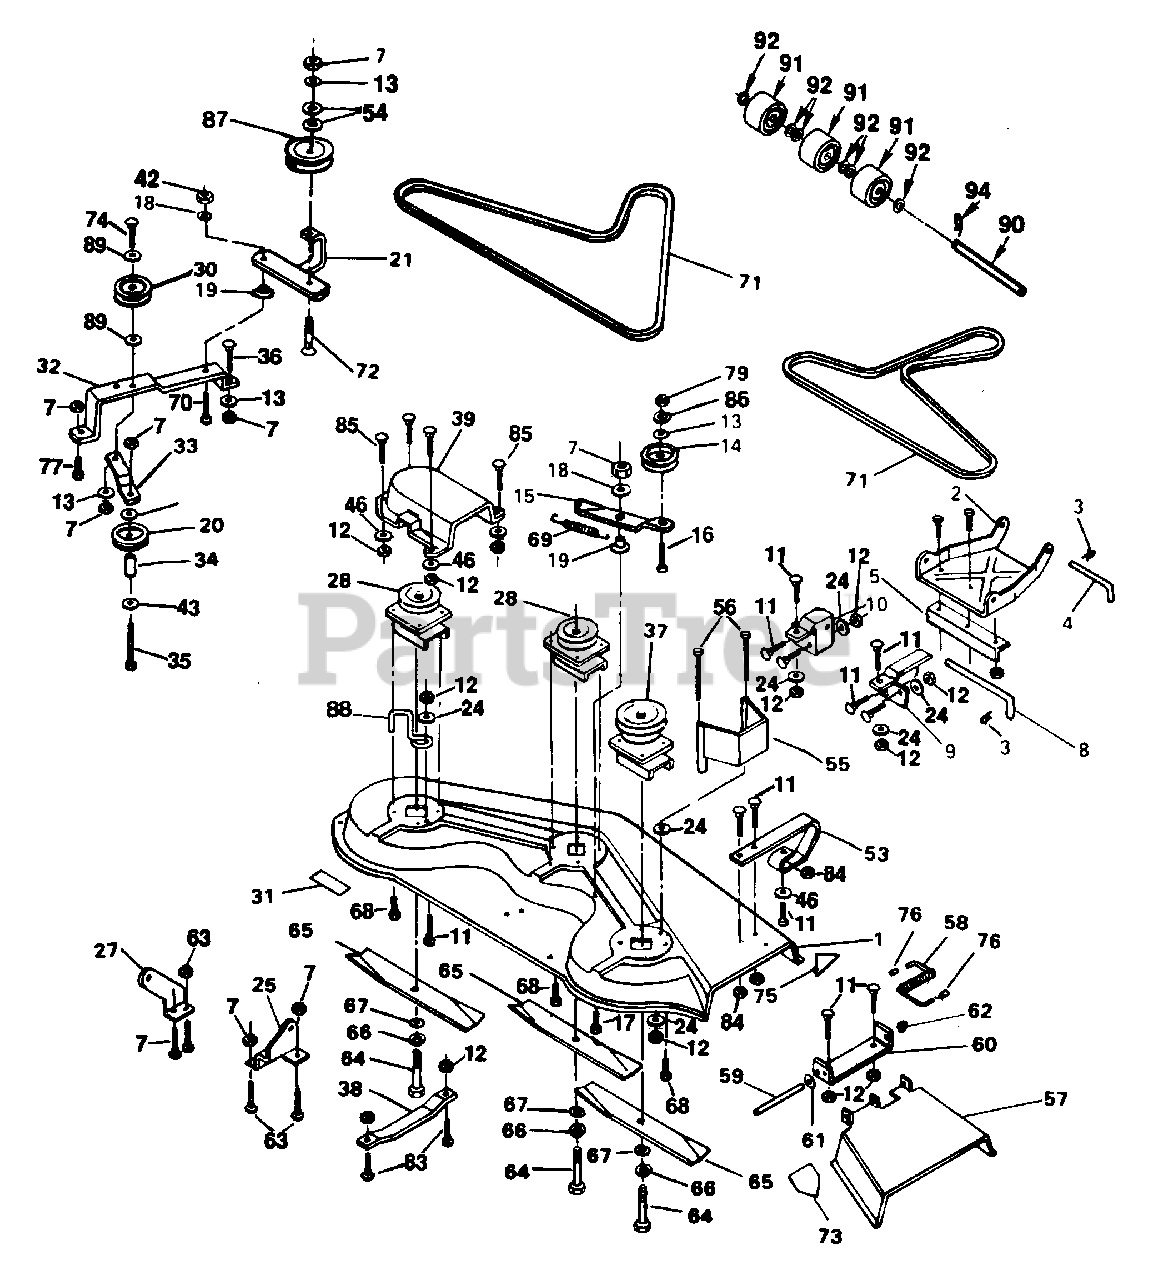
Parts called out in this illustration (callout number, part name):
1	Mower Housing (AYP part number)
2	Parallel Link (AYP part number)
3	Spring Retainer (AYP part number)
4	Front Hinge Pin (AYP part number)
7	Locknut
8	Rear Hinge Pin (AYP part number)
9	R.H. Lift Bracket (AYP part number)
10	L.H. Lift Bracket (AYP part number)
11	Carriage Bolt 5/16-18 x 3/4
12	Locknut
13	Washer (AYP part number)
14	Flat Idler (AYP part number)
15	Deck Arm Idler (AYP part number)
17	Hex Bolt 3/8-16 x 1-1/4 (AYP part number)
18	Wear Washer (AYP part number)
19	Spacer (AYP part number)
20	Idler Pulley (AYP part number)
21	Idler Arm (AYP part number)
24	Washer (AYP part number)
25	R.H. Rear Suspension Bracket (AYP part number)
27	L.H. Rear Suspension Bracket (AYP part number)
28	Secondary Mandrel (AYP part number)
30	Idler Pulley (AYP part number)
31	V-Belt Decal (AYP part number)
32	Idler Support Bar (AYP part number)
33	Deck Idler Brace (AYP part number)
34	Spacer (AYP part number)
35	Hex Bolt 3/8-16 x 3 (AYP part number)
36	Carriage Bolt 3/8-16 x 1 (AYP part number)
37	Primary Mandrel (AYP part number)
38	L.H. Runner (AYP part number)
39	Guard (AYP part number)
42	Centerlock Nut (AYP part number)
43	Washer (AYP part number)
46	Washer 11/32 x 11/16 x 16 Ga. (AYP part number)
53	R.H. Runner (AYP part number)
54	Washer (AYP part number)
55	R.H. Belt Guard (AYP part number)
56	Hex Bolt (AYP part number)
57	Discharge Guard (AYP part number)
58	Deflector Spring (AYP part number)
59	Hinge Rod (AYP part number)
60	Deflector Bracket (AYP part number)
61	Washer (AYP part number)
62	Push Nut (AYP part number)
63	Carriage Bolt 3/8-16 x 3/4 (AYP part number)
64	Hex Bolt 3/8-24 x 1-1/2 Gr. 5 (AYP part number)
65	Blade (AYP part number)
66	Lock Washer 3/8 (AYP part number)
67	Washer (AYP part number)
68	Thd. Roll. Washer Hd. Hex Screw (AYP part number)
69	Extension Spring (AYP part number)
70	Carriage Bolt 3/8-16 x 1-1/2 (AYP part number)
71	V-Belt (AYP part number)
72	Carriage Bolt 3/8-16 x 2-1/2 (AYP part number)
73	Warning Decal (AYP part number)
74	Carriage Bolt 3/8-16 x 1-3/4 (AYP part number)
76	Sleeve Cap (AYP part number)
77	Hex Bolt 3/8-16 x 1 (AYP part number)
79	Hex Nut 3/8-16 (AYP part number)
83	Carriage Bolt 5/16-18 x 5/8 (AYP part number)
84	Locknut (AYP part number)
85	Sq. Neck Round Hd. Bolt (AYP part number)
86	Lock Washer (AYP part number)
87	Idler Pulley (AYP part number)
88	Belt Keeper (AYP part number)
89	Washer (AYP part number)
90	Pivot Pin (AYP part number)
91	Nose Roller (AYP part number)
92	Washer (AYP part number)
93	Washer (AYP part number)
94	Cotter Pin (AYP part number)
